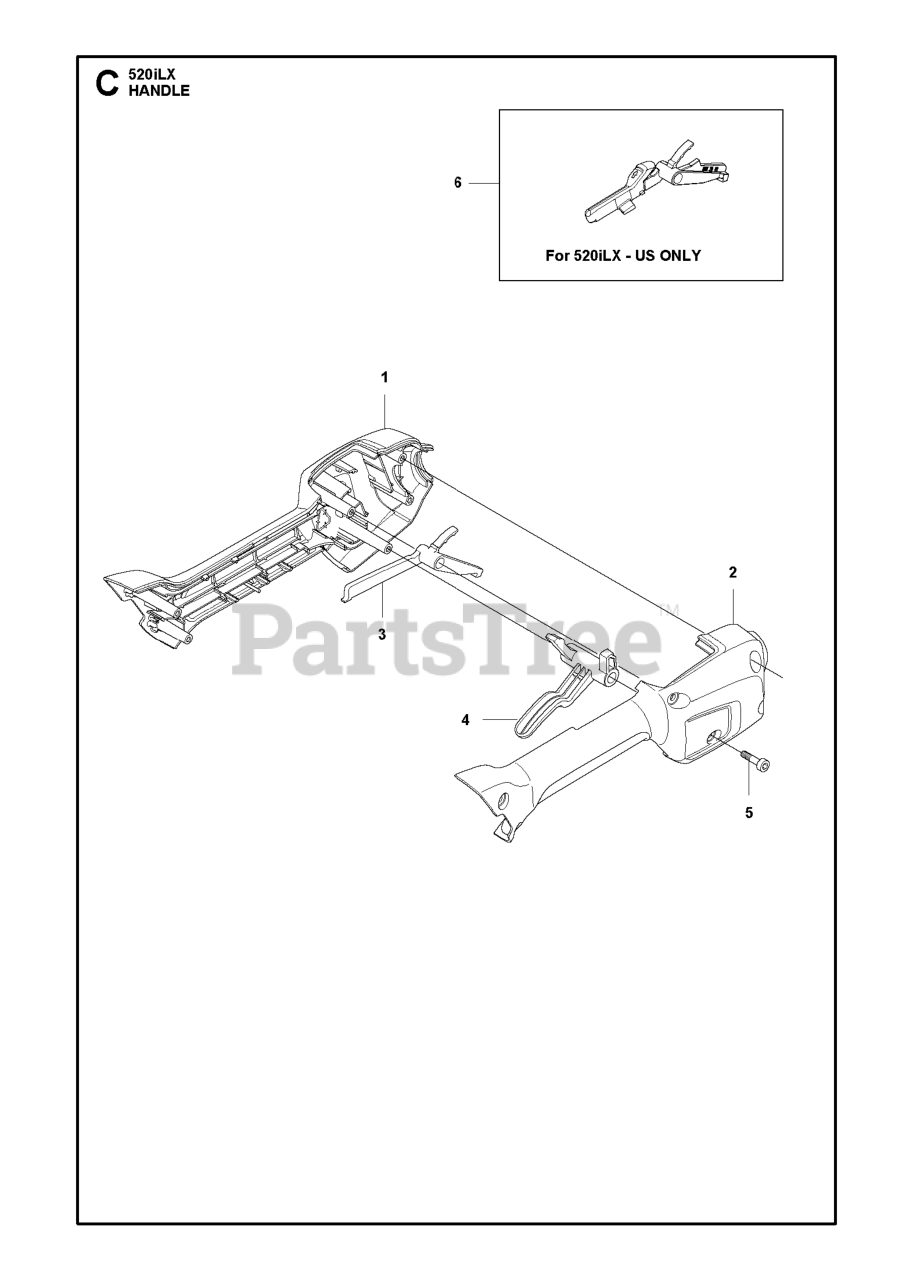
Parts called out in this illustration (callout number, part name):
1	HANDLE HALF LEFT
2	HANDLE HALF RIGHT
3	THROTTLE LOCKOUT
5	SCREW
6	THROTTLE LOCKOUT ASSEMBLY DISS
